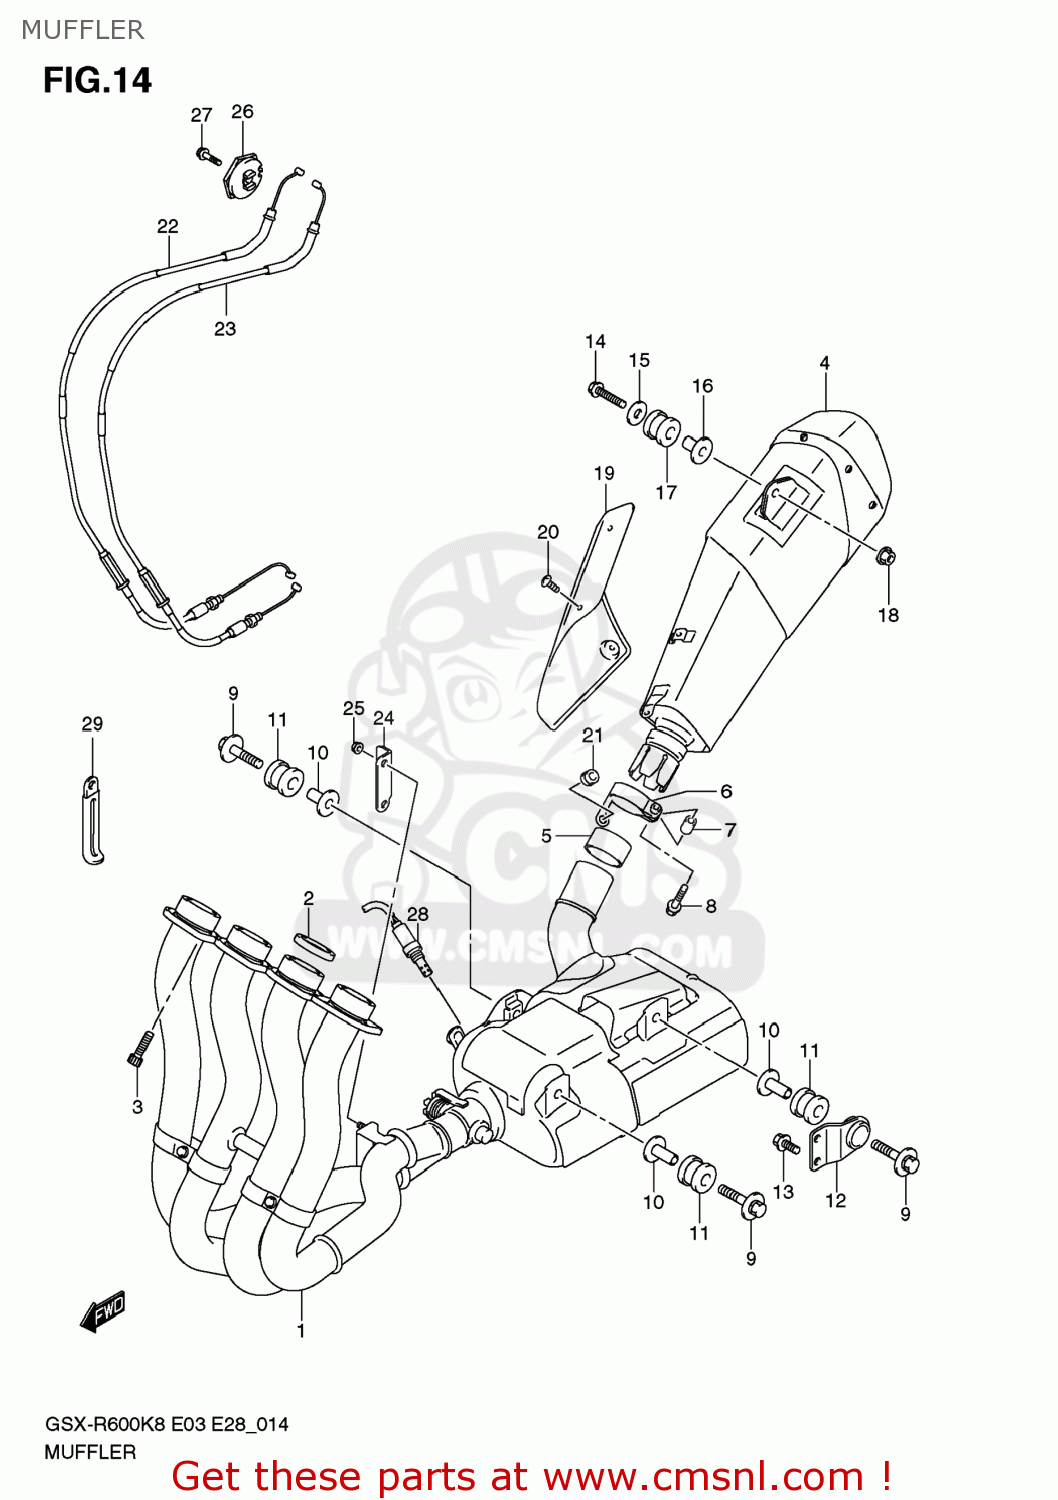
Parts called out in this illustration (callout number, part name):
1	EXHAUST
2	GASKET,EXHAUST PIPE
3	BOLT
4	BODY,MUFFLER
5	CONNECTOR,MUFFLER
6	CLAMP,MUFFLER CONNECTOR
7	SPACER,MUFFLER
8	BOLT(8X40)
9	BOLT(8X45)
10	SPACER (8.6X12
11	CUSHION
12	BRACKET,CHAMBER SPRT
13	BOLT
14	BOLT(8X45)
15	WASHER(8.5X28X1.5)
16	SPACER(8.6X12X24.2)
17	CUSHION
18	NUT
19	COVER,MUFFLER FR
20	SCREW(6X10)
21	CUSHION
22	CABLE,EXHAUST VALVE NO.1
23	CABLE,EXHAUST VALVE NO.2
24	BRACKET,EXHAUST VALVE CABLE
25	NUT
26	PULLEY CONTROL
27	BOLT
28	SENSOR,OXYGEN
29	CLAMP(L:45)
